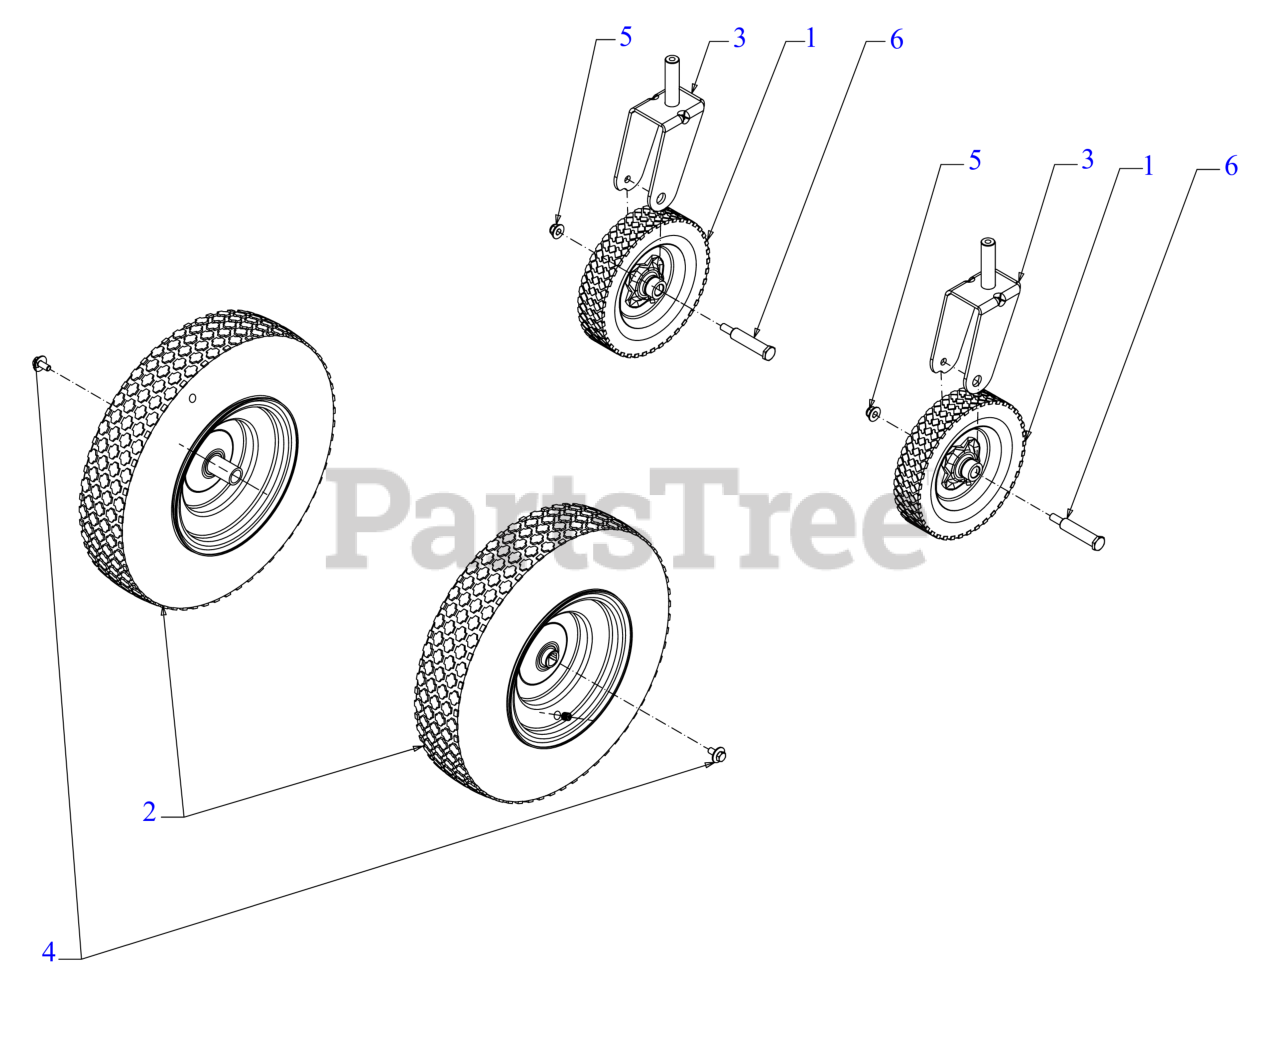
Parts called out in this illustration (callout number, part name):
1	CASTER WHEEL (8x1.75)
2	COMPLETE WHEEL (16x4x8)
4	SCREW 5/16-24 x .750 GR5
6	SHOULDER SCREW:.625 x 2.515 x 1.00
